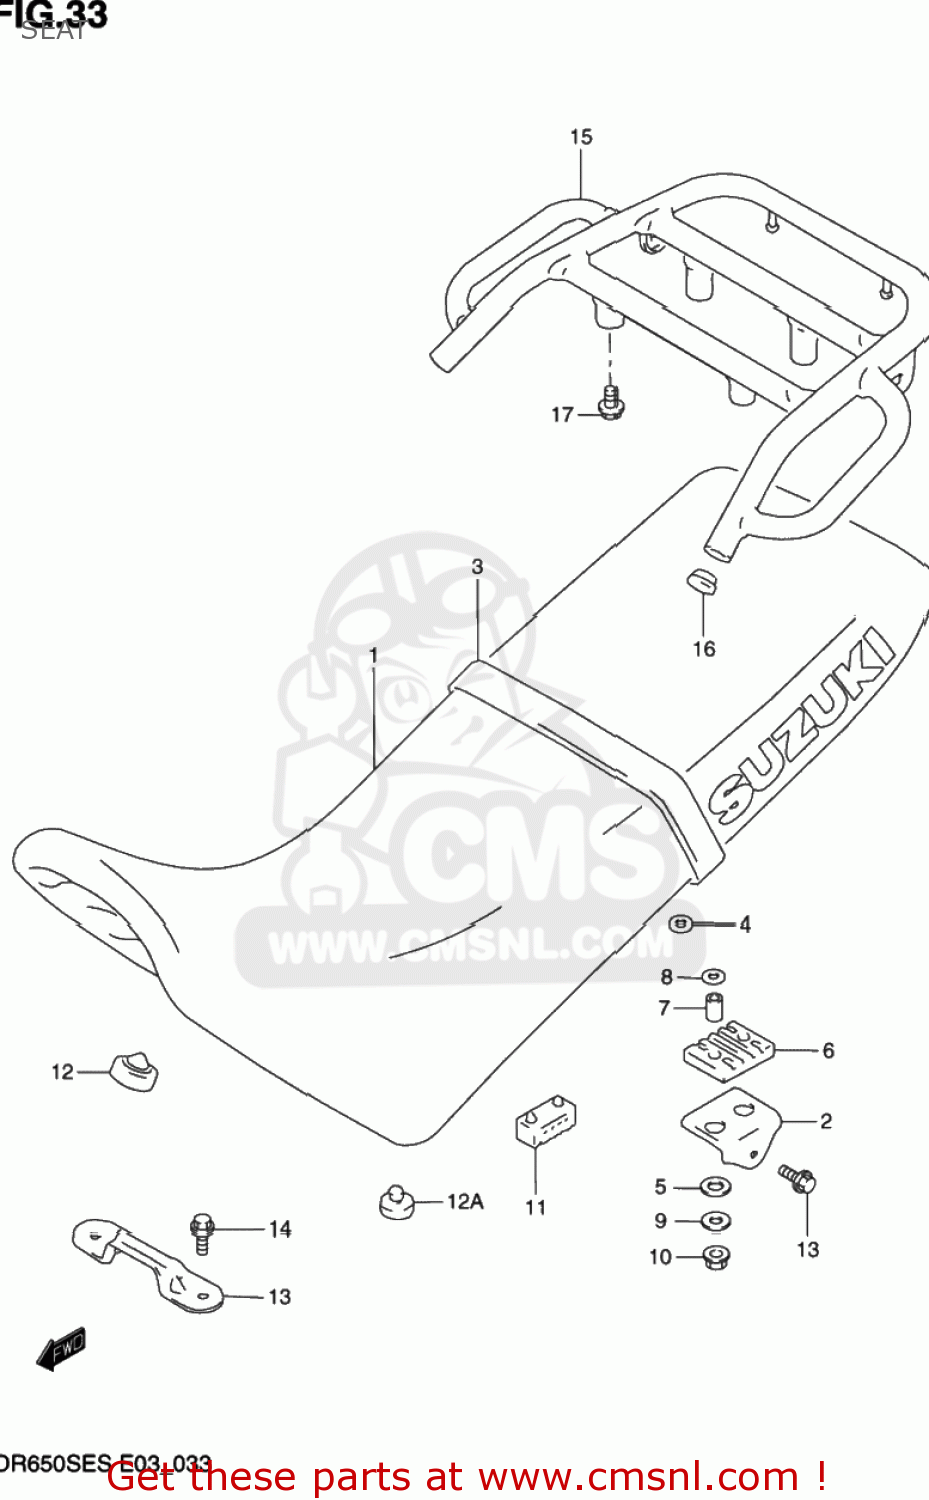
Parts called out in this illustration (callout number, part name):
1	SEAT ASSEMBLY
2	BRACKET,SEAT
3	BAND,SEAT
4	WASHER
5	CUSHION,SEAT FR
6	CUSHION,FR PLATE
7	SPACER,SEAT BRACKET
8	WASHER
9	WASHER, LOWER
10	NUT
11	CUSHION,SEAT(40X20X15)
12	CUSHION,FRONT
12A	CUSHION
13	PLATE,SEAT FR HOOK
14	BOLT
15	CARRIER,SPORT
16	CAP(OD:19)
17	BOLT
